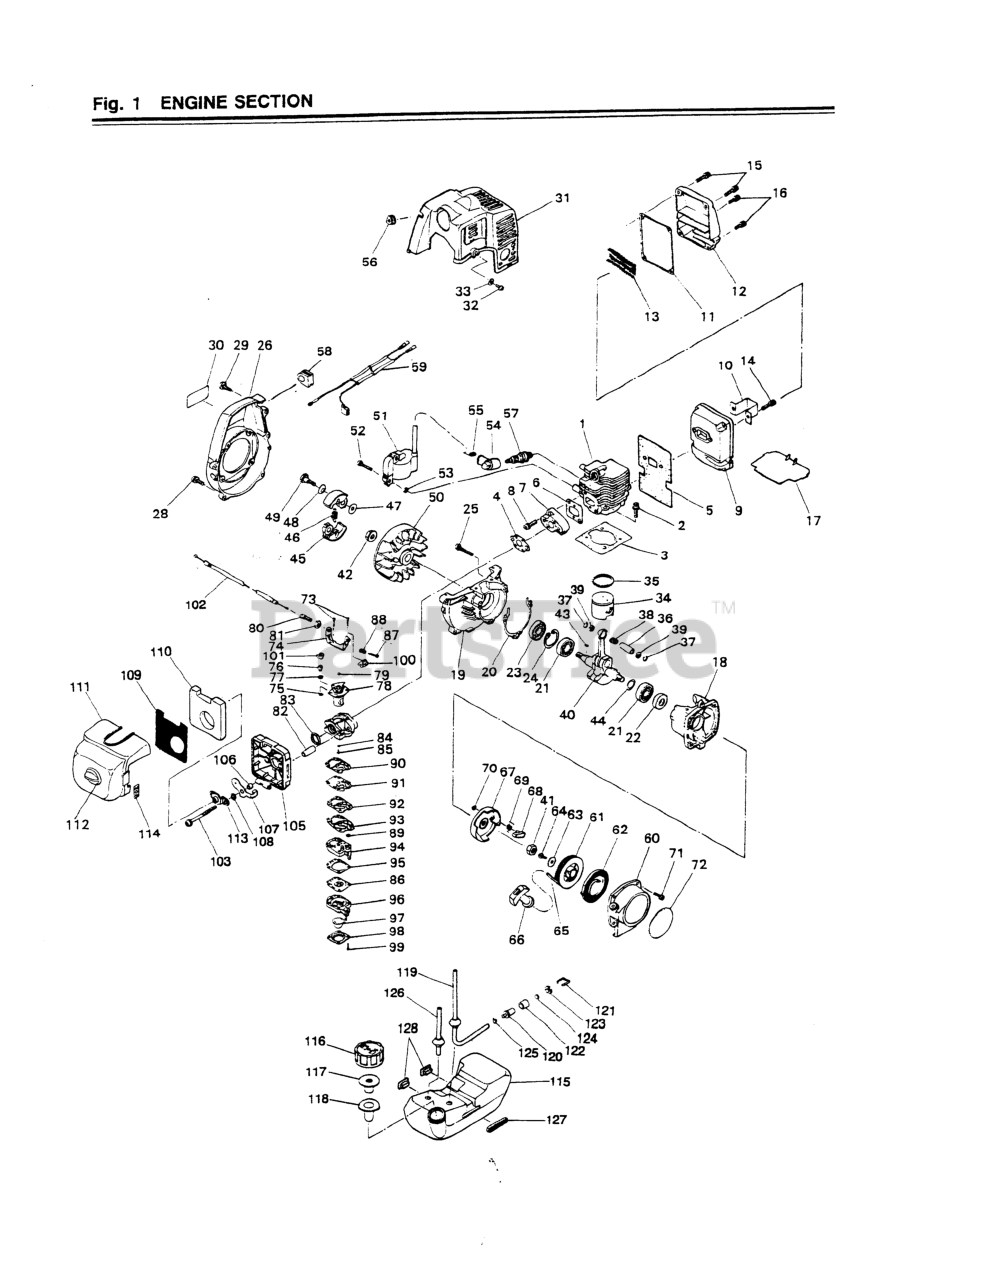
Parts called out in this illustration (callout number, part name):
2	BOLT, M5 X 22
8	SCREW, M5 X 20
13	ARRESTER
14	BOLT, M6 X 18
15	BOLT, M5 X 22
16	BOLT (USE 3310-31720)
18	CRANKCASE (RPLS -21100)
19	CRANKCASE (RPLS -21100)
21	BEARING
23	SEAL, OIL (RPLS 1140-21220)
24	RING, SNAP, M28 x 1.2
25	SCREW, M5 x 30
28	SCREW, M5 X 20
29	SCREW, HOUSING
32	SCREW, M4 x 12
33	WASHER
34	PISTON
35	RING, PISTON (RPLS 1850-41210)
36	PIN, PISTON 5x8x26
39	WASHER
43	KEY
44	SHIM (NO LONGER AVAILABLE)
47	WASHER, FLAT (USE 182303)
49	BOLT
52	SCREW, M4 X 22
55	SPRING
56	GROMMET
61	REEL
62	SPRING, SPIRAL
63	WASHER (NO LONGER AVAIL)
69	SPRING, RETURN
70	E-RING
71	SCREW, M4 X 16
72	LABEL
73	SCREW
75	RING
76	SWIVEL (USE -06040)
77	WASHER
78	VALVE ASSY (NO L0NGER AVAIL)
79	PLUG NEEDLE
81	NUT, CABLE ADJUSTER
82	SLEEVE, MOUNT
83	RING, PACKING (NLA)
84	RING, O
86	DIAPHRAGM (USE 4810-81260)
87	SCREW, IDLE AD
88	SPRING, IDLE A
89	SCREEN
90	GASKET, PUMP
91	DIAPHRAGM
92	PLATE, PUMP (NLA)
93	GASKET, PLATE
94	KIT ONLY
95	KIT ONLY
96	BODY
97	PUMP, PRIMING
98	COVER
99	SCREW
101	CAP, CABLE END
102	CABLE COMP (RPLS 1633-83100)
105	BODY (RPLS -82110)
106	SLEEVE
109	SCREEN
110	ELEMENT
112	KNOB (RPLS 1600-33140)
114	LABEL
116	CAP (USE 5601-85201)
117	VALVE (NO LONGER AVAILABLE)
119	PIPE COMP (NO LONGER AVAIL)
120	5500-85400 (RRLS. 1750-85300)
121	5500-85400 (RRLS. 1750-85300)
123	RETAINER
125	CLIP (REPLACES 2841-31280)
128	CUSHION (F)
